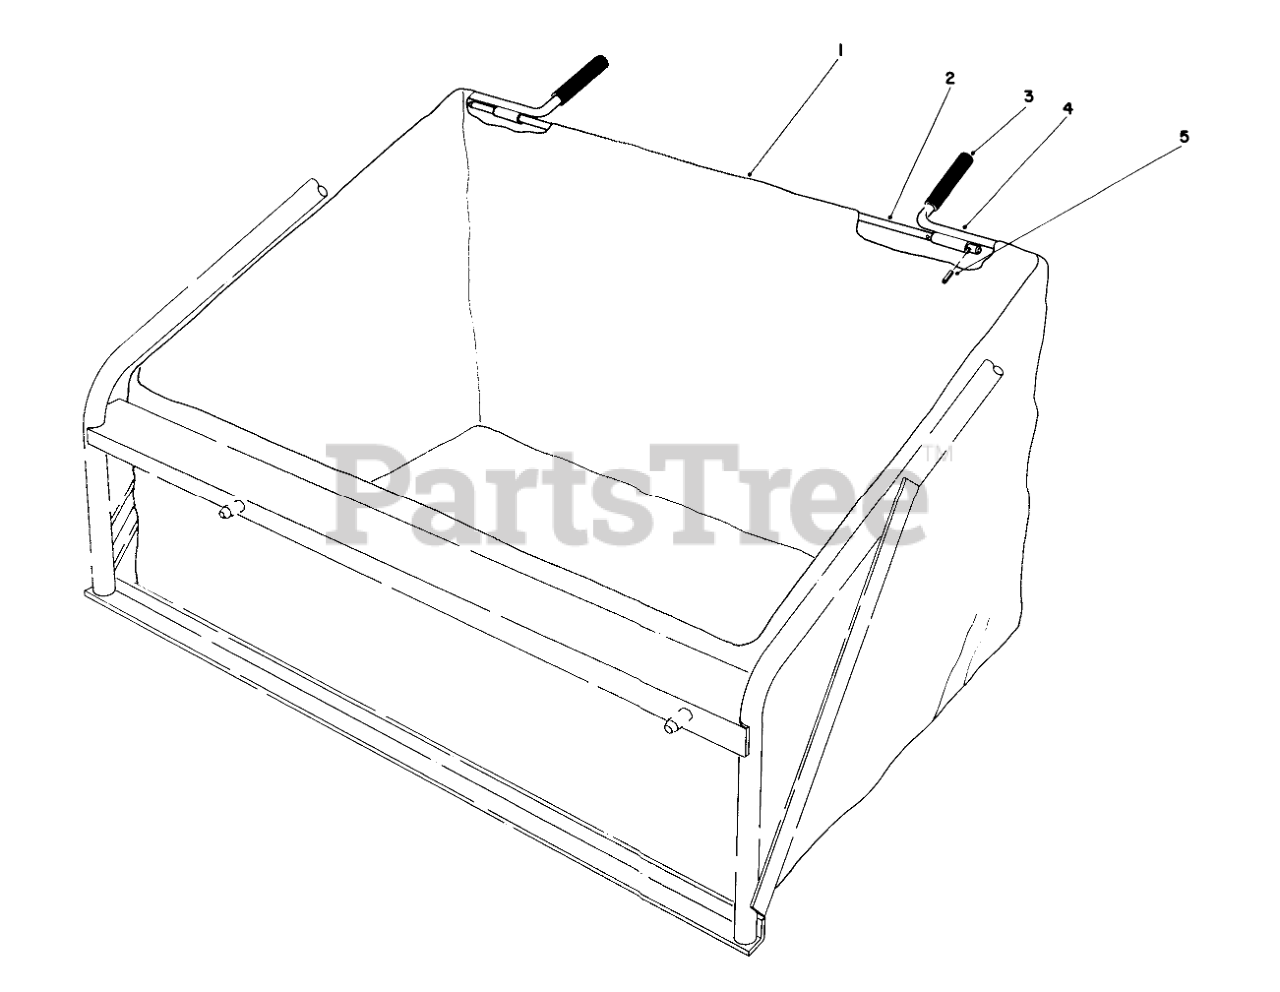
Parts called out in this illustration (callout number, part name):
1	Bag-Leaf Catcher
2	BAG FRAME ROD
3	BAG HANDLE GRIP
4	BAG FRAME WA B
5	PIN-ROLL
